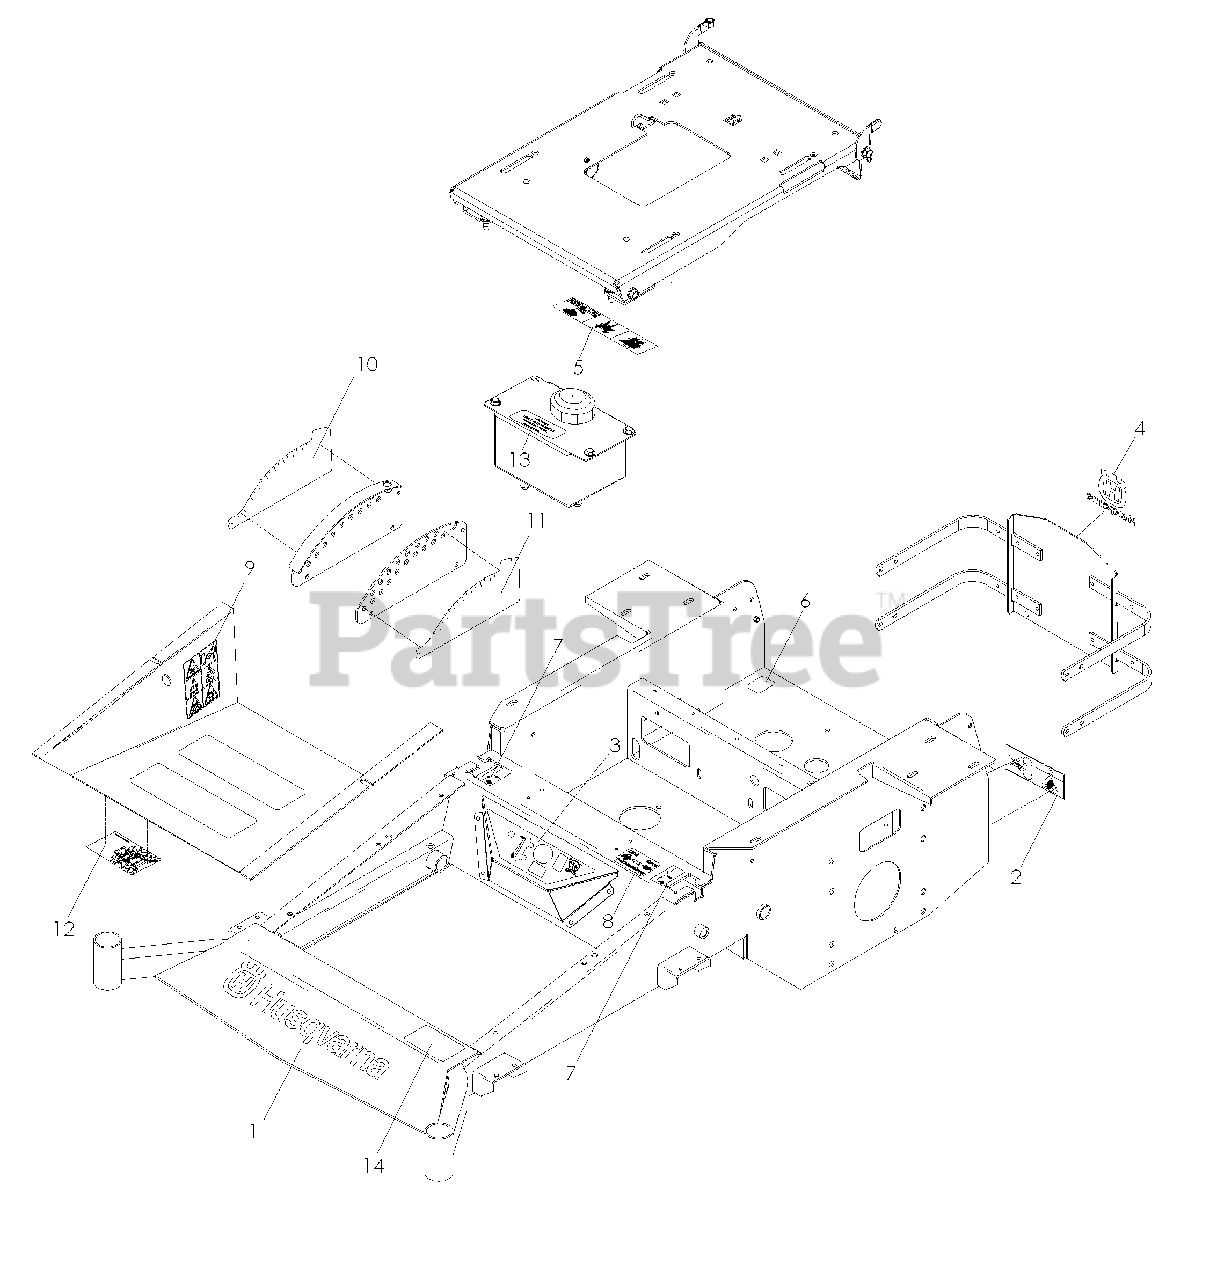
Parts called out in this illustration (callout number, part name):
1	DECAL, HUSQ. 15" BLUE
2	DECAL, DANGER
3	DECAL, CONSOLE
4	DECAL, HUSQ. SILVER
5	DECAL, BATTERY WARNING
6	DECAL, PROP 65
7	DECAL, MOTION CONTROL
8	DECAL, TRACKING
9	DECAL, WARNING
10	DECAL, HEIGHT
11	DECAL, HEIGHT
12	DECAL, SERVICE
13	DECAL, OIL TANK
14	DECAL, LZ25
14	DECAL, LZ30
